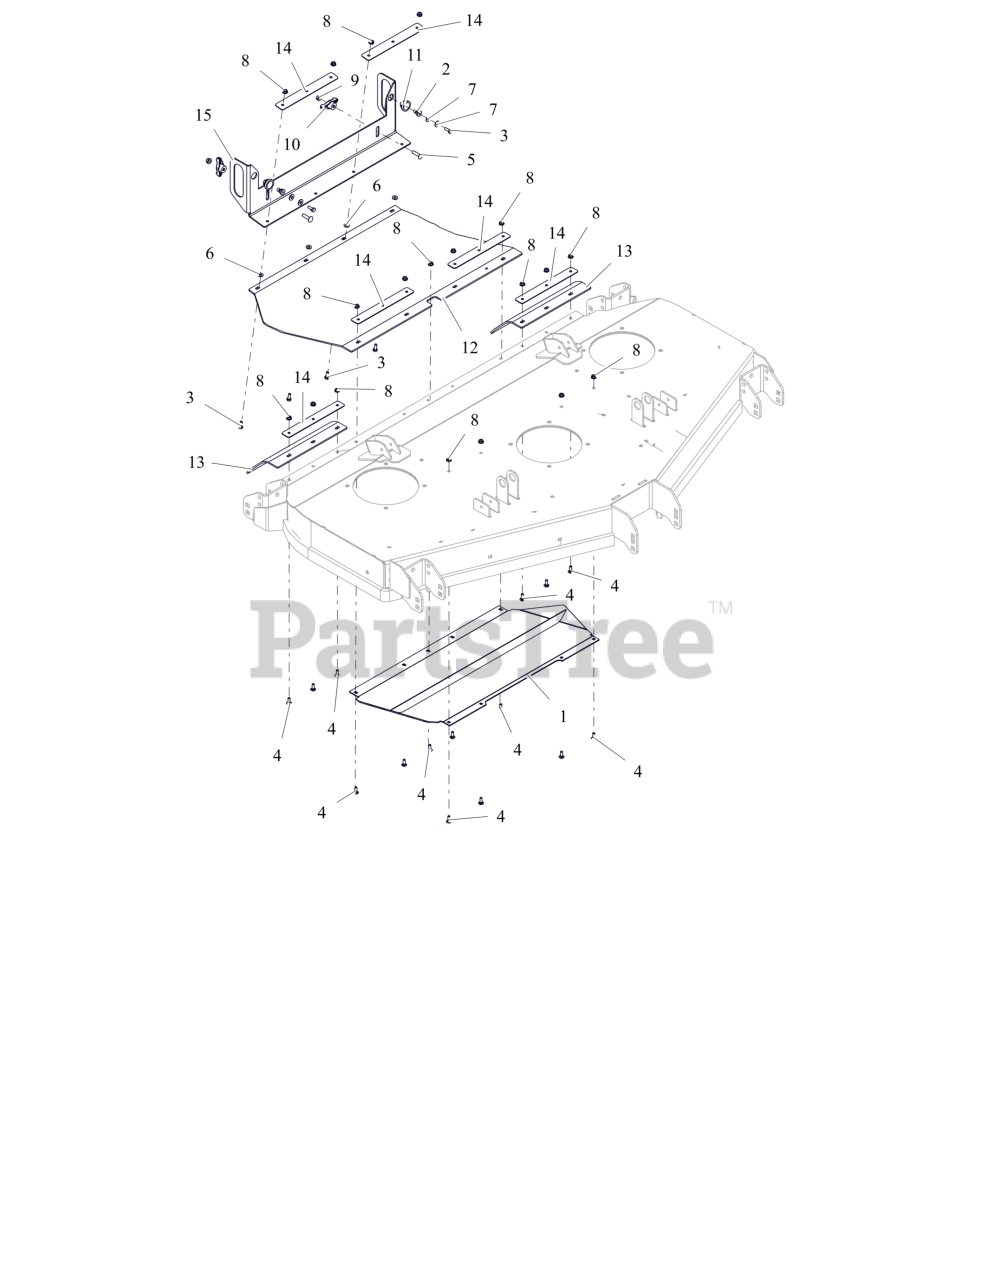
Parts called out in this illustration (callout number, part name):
1	WLDMT, DEFLECTOR BAFFLE (ORANGE)
2	STUD, BALL FEMALE .250-20 THREAD
3	BLT, HEX .25-20X.75 G5 ZCC
4	BLT, RHSN .25-20X.750 G5 ZCC
5	BLT, RHSSN.31-18X1.25 G5 ZCC
6	WSHR,FLT .281X.625X.065 ZCC
7	WSHR, FLT .312X.734X.065 ZCC
8	NUT-LK-CTR-FLG .25-20 ZC120
9	NUT,LK-CTR-FLG .31-18 GF ZCC
10	KNOB,WING .31-18 UNC NYL/TALC
11	COUPLING, RUBBER PUSH-IN
12	CHUTE, REAR DISCHARGE EV
13	CHUTE, TIRE REAR DISCHARGE
14	PLATE, CHUTE MTG (BLACK)
15	HANDLE, CHUTE MOUNTING (ORANGE)
